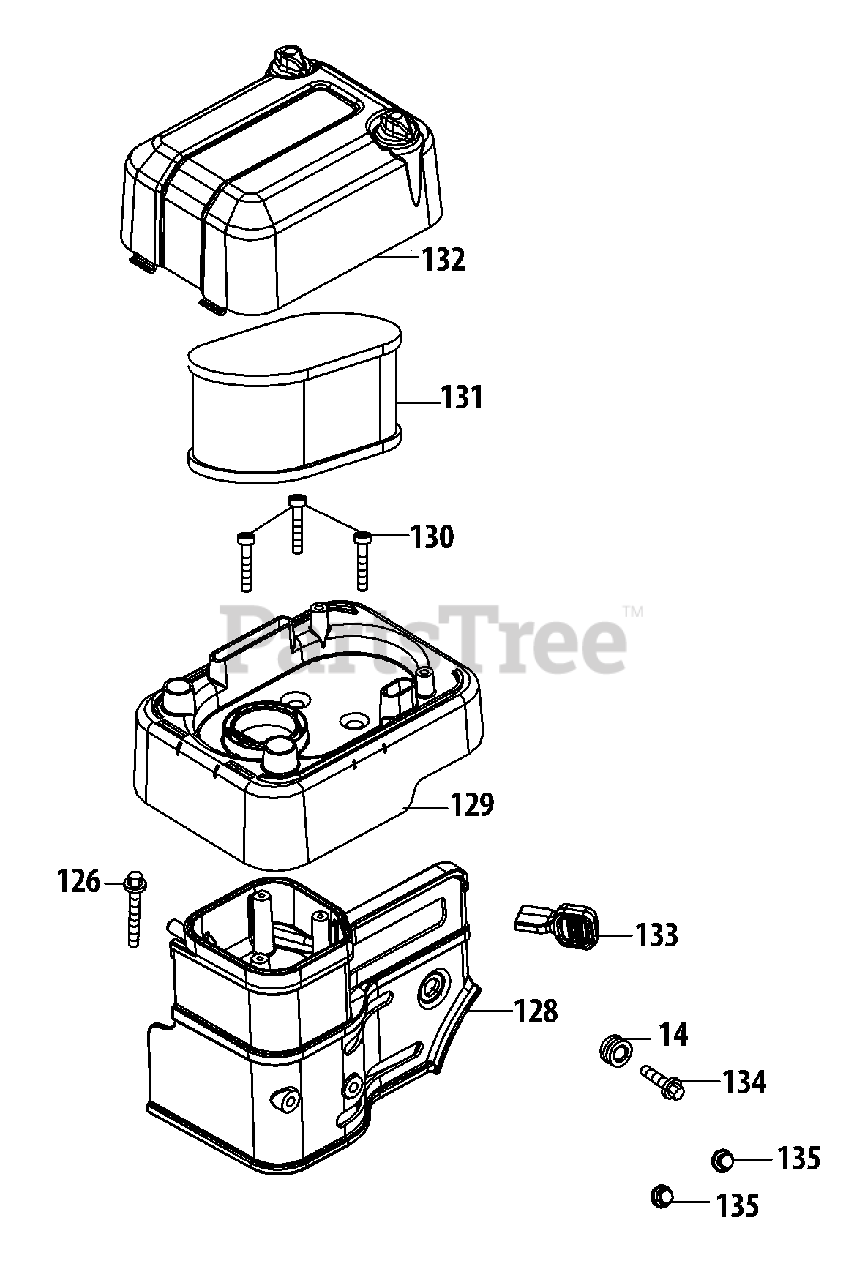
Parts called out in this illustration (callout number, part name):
14	Isolator Bushing
126	Bolt M6×30
128	Air Filter Base
129	Middle Air Filterbox
130	Countersunk Screw
131	Air Filter Cover
132	Air Filter Cover Assembly
133	Throttle Control Knob
134	Bolt M6×16
